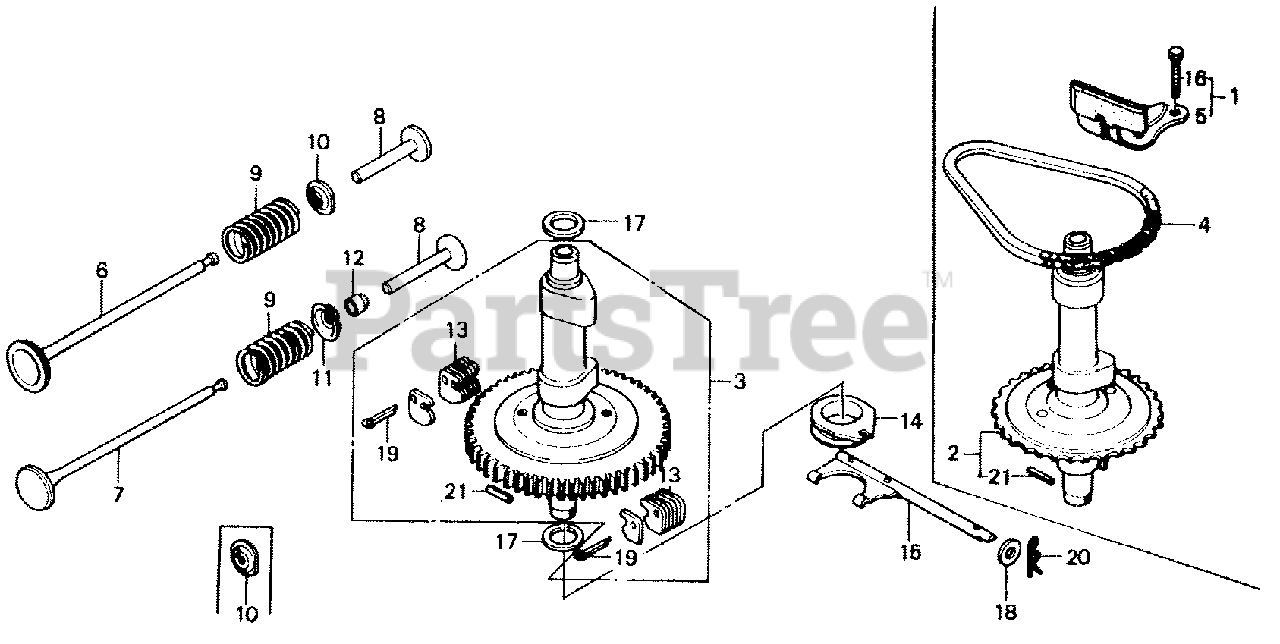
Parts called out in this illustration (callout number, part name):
3	CAMSHAFT ASSY.
6	VALVE, IN.
7	VALVE, EX.
8	LIFTER, VALVE (45.89MM)
8	LIFTER, VALVE (46.04MM)
8	LIFTER, VALVE (46.19MM)
8	LIFTER, VALVE (46.34MM)
9	SPRING, VALVE
10	RETAINER, VALVE SPRING
13	WEIGHT, GOVERNOR
14	SLIDER, GOVERNOR
15	SHAFT, GOVERNOR
17	WASHER, THRUST (18MM)
18	WASHER, PLAIN (6MM)
19	PIN, COTTER (3.0X45)
20	PIN, LOCK (6MM)
21	PIN, SPRING (2.5X16)
